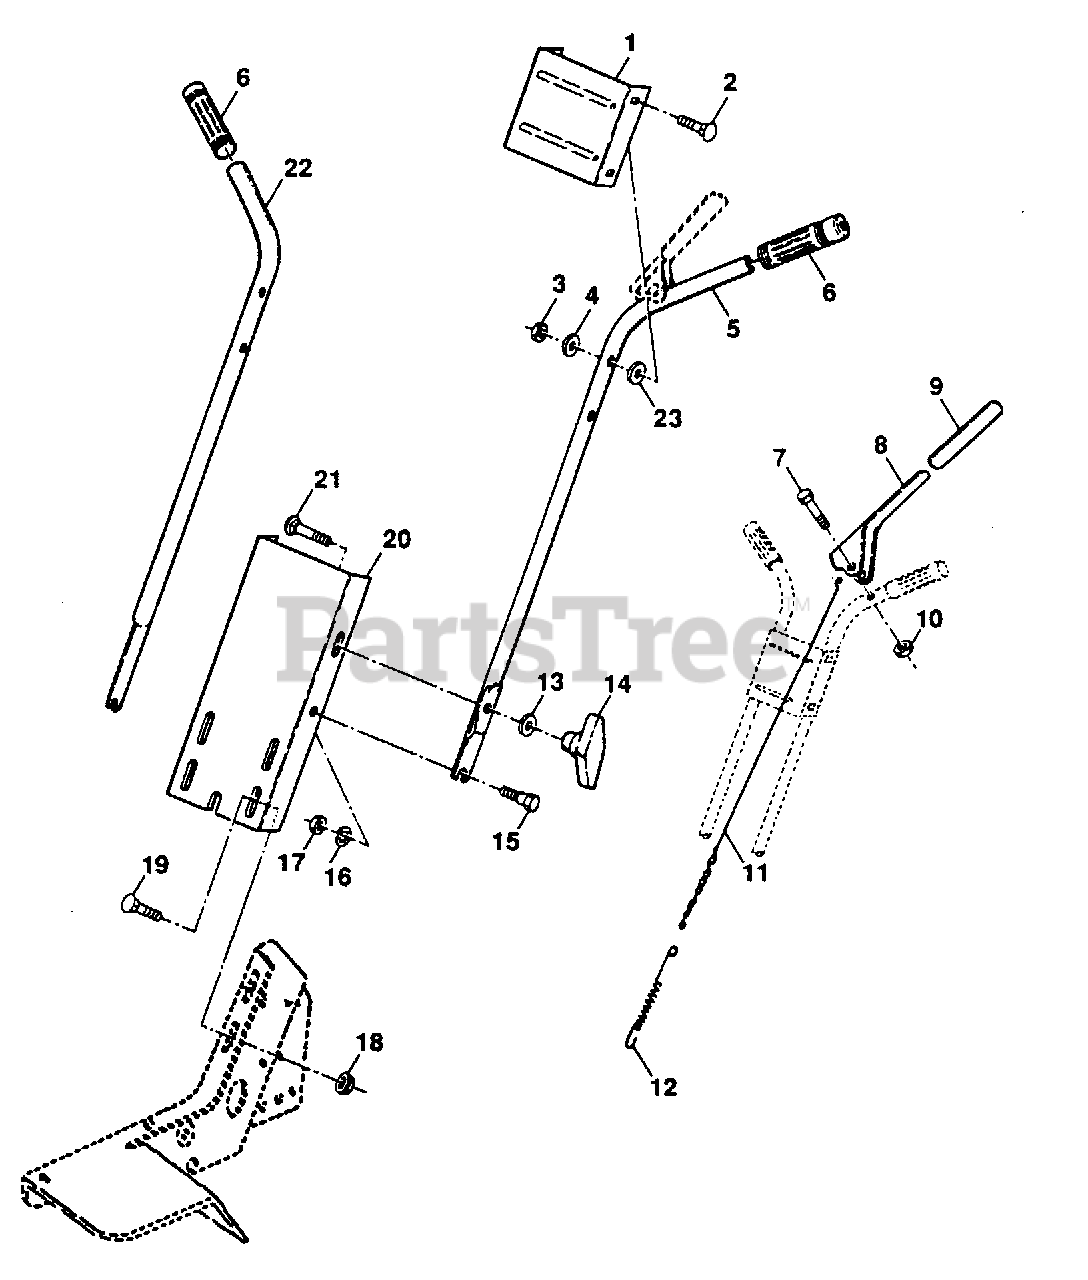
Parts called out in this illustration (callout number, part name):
1	Bracket, Handle (AYP part number)
2	Bolt, Carriage 5/16-18 UNC x 1-1/2 (AYP part number)
3	Locknut, Crown 5/16-18
4	Washer 11/32 x 11/16 x 16 Ga. (AYP part number)
5	Handle, L.H. (AYP part number)
6	Grip, Handle (AYP part number)
7	Bolt, Hex 5/16-18 x 1-1/2 (AYP part number)
8	Lever, Control, Tine (AYP part number)
9	Grip, Lever (AYP part number)
10	Nut, Hex (AYP part number)
11	Cable, Control, Tine (AYP part number)
12	Spring, Extension (AYP part number)
13	Washer 3/8 x 7/8 x 14 Ga. (AYP part number)
14	Knob, Handle (AYP part number)
15	Bolt, Shoulder 5/16-18 x 3/4 (AYP part number)
16	Washer, Lock 5/16 (AYP part number)
17	Nut, Hex 5/16-18 (AYP part number)
18	Nut, Flanged 5/16-18 (AYP part number)
19	Bolt, Carriage 5/16-18 x 3/4 Gr. 5
20	Panel, Handle (AYP part number)
21	Bolt, Carriage 5/16-18 x 1 (AYP part number)
22	Handle, R.H. (AYP part number)
23	Washer 13/32 x 13/16 x 12 Ga. (AYP part number)
